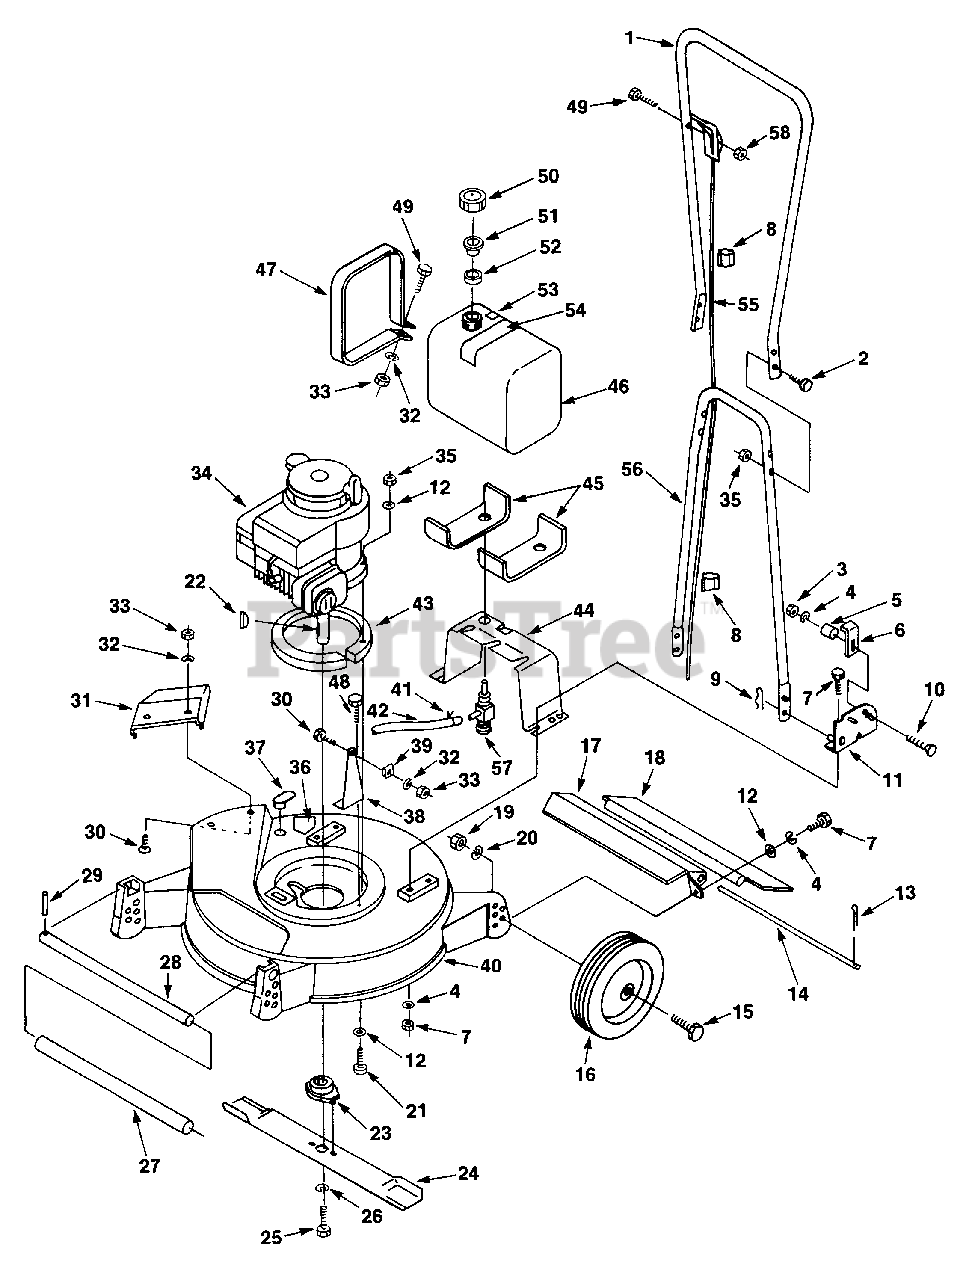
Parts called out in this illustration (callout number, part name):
1	HANDLE- Upper
2	BOLT- Sq. neck (5/16-18 x 1 1/2")
3	NUT- Hex (5/16-18)
4	WASHER- Lock (5/16")
5	STOP- Hanger
6	BRACKET- Stop
7	SCREW- Hex hd. (5/16-18 x 1")
8	CLIP- Handle
9	HAIR PIN- Cotter
10	BOLT- Sq. Neck (5/16-18 x 1 1/4")
11	BRACKET- R.H.
12	WASHER- Flat (5/16")
13	PIN- Cotter
14	ROD- Drag flap
15	SCREW- Hex hd. (1/2-20 x 3 1/2")
16	WHEEL & TIRE ASSEMBLY
17	DEFLECTOR
18	FLAP- Drag
19	NUT- Hex (1/2-20)
20	WASHER- Lock (1/2")
21	SCREW- Hex hd. (5/16-18 x 2 1/2")
22	KEY- Morton
23	ADAPTER- Blade
24	BAR- Cutter
25	SCREW- Hex hd. (3/8-24 x 1 1/2")
26	WASHER- Lock (3/8")
27	BUMPER- Front
28	ROD- Front
29	PIN- Roll
30	SCREW- Hex hd. (1/4-20 x 3/4")
31	SHIELD- Deflector
32	WASHER- Lock (1/4")
33	NUT- Hex (1/4-20)
34	ENGINE- 5 H.P.
35	NUT- Hex (5/16-18)
36	DECAL- Warning
37	PLUG- Wash hole
38	BRACKET- Spacer
39	CLAMP- Throttle
40	DECK
41	RING- Fuel line
42	LINE- Fuel
43	SPACER- Engine
44	SUPPORT- Tank
45	SUPPORT- Tank
46	TANK- Fuel
47	STRAP- Fuel tank
48	SCREW- Hex hd. (10-24 x 1/2")
49	SCREW- Hex hd. (1/4-20 x 1 1/2")
50	CAP- Fuel tank
51	BAFFLE- Fuel cap
52	GASKET- Fuel cap
53	DECAL- Refueling Instruction
54	DECAL- Engine Instruction
55	CONTROL- Throttle
56	HANDLE- Lower
57	VALVE- Shut off
58	NUT- Hex locking (1/4-20)
